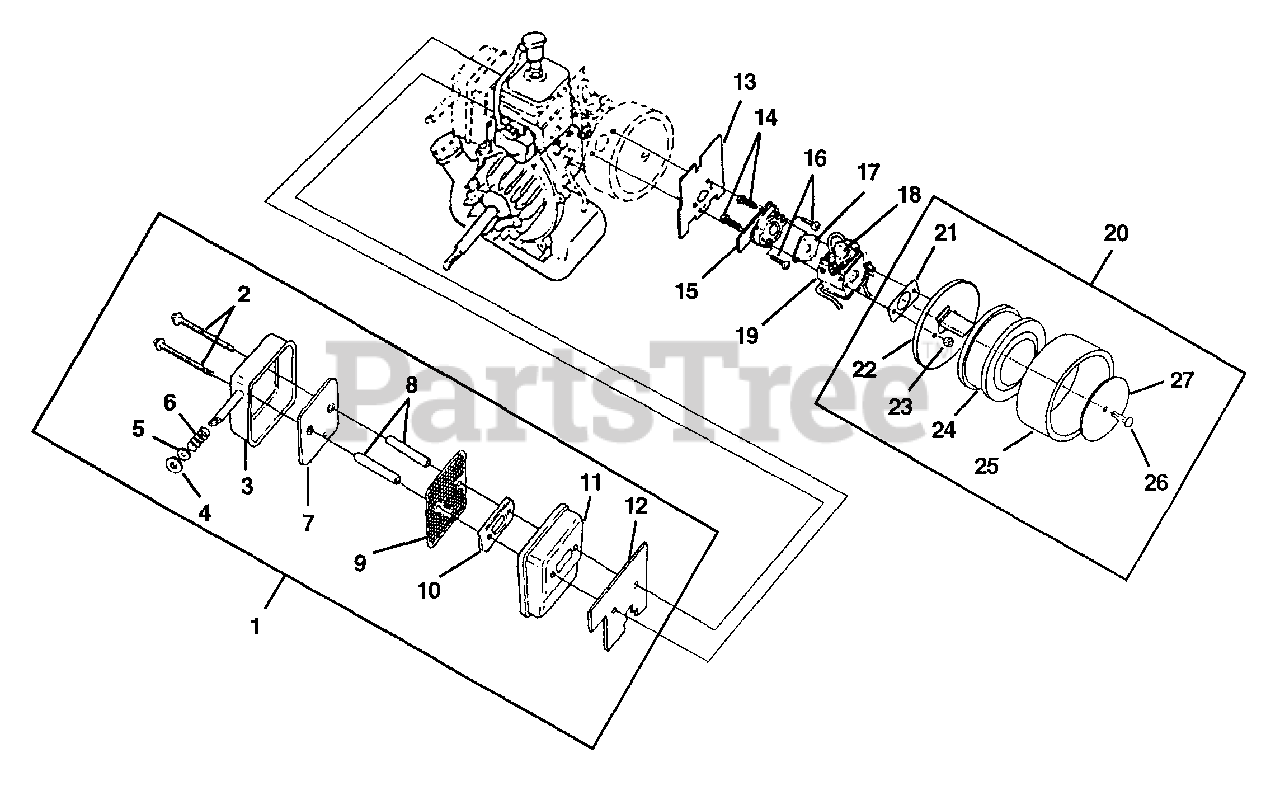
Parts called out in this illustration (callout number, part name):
1	MUFFLER ASSY.
2	SCREW, (SEMS HEX HD 10-24 X 2 1/2")
3	MUFFLER COVER
4	WASHER, INSULATING
5	WASHER, FLAT
6	SPRING, COMPRESSION
7	DEFLECTOR, MUFFLER
8	SPACER, MUFFLER
9	SCREEN, SPARK ARRESTOR
10	PLATE, REINFORCING
11	BODY, MUFFLER
12	GASKET, MUFFLER
13	GASKET, HEAT DAM
14	SCREW, MACHINE 10-24 X 2 1/4
15	HEAT DAM
16	SCREW, SEMS (10-24 x 1.110)
17	GASKET, CARBURETOR
18	PRIMER BULB (WALBRO)
19	CARBURETOR
20	AIR FILTER ASSY.
21	GASKET, CARBURETOR
22	PLATE, FILTER
23	NUT, MACHINE 10-24
24	AIR FILTER
25	PRE-FILTER
26	SCREW, (MACHINE 10-24 X 3/4")
27	WASHER, FILTER
